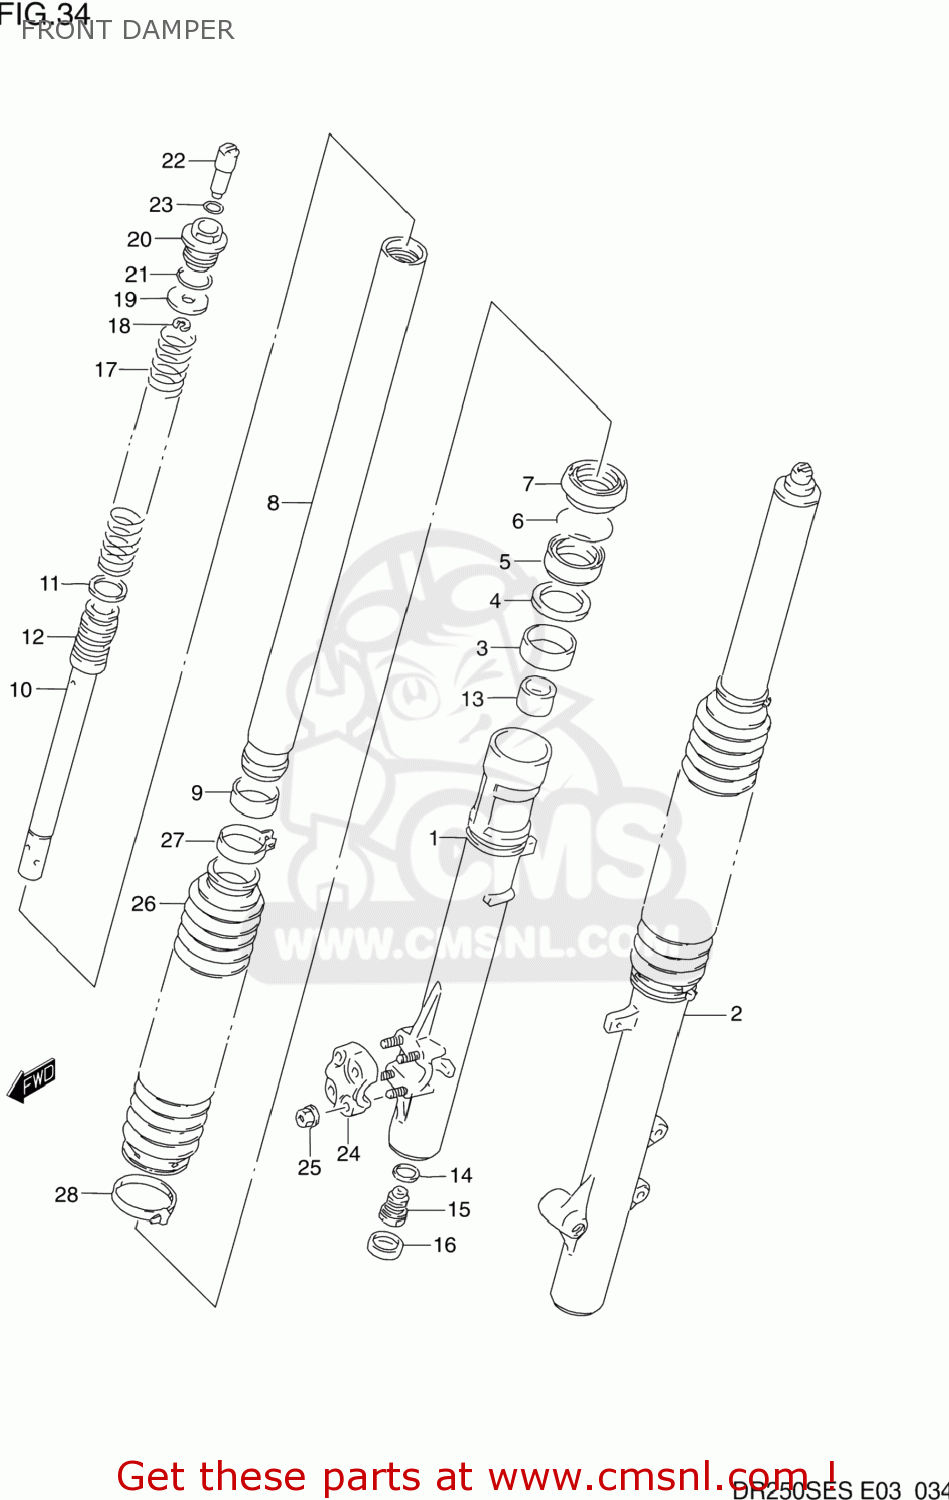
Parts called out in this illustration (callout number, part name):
1	TUBE,OUTER,R
2	TUBE,OUTER,L
3	BUSH,GUIDE
4	SPACER,SEAL
5	SEAL,OIL
6	CIRCLIP,FORK OIL SEAL
7	DUST SEAL
8	TUBE,INNER
9	BUSH,SLIDE
10	CYLINDER
11	RING,PISTON
12	SPRING,REBOUND
13	PIECE,OIL LOCK
14	GASKET (NAS)
15	BOLT,LWR
16	CAP,LOWER
17	SPRING,MAIN
18	E RING
19	SEAT,SPRING
20	BOLT,FORK
21	O RING
22	ADJUSTER,SPRING
23	O RING
24	HOLDER,AXLE
25	NUT,HOLDER
26	BOOT
27	BAND,BOOT UPR
28	BAND,BOOT LWR
